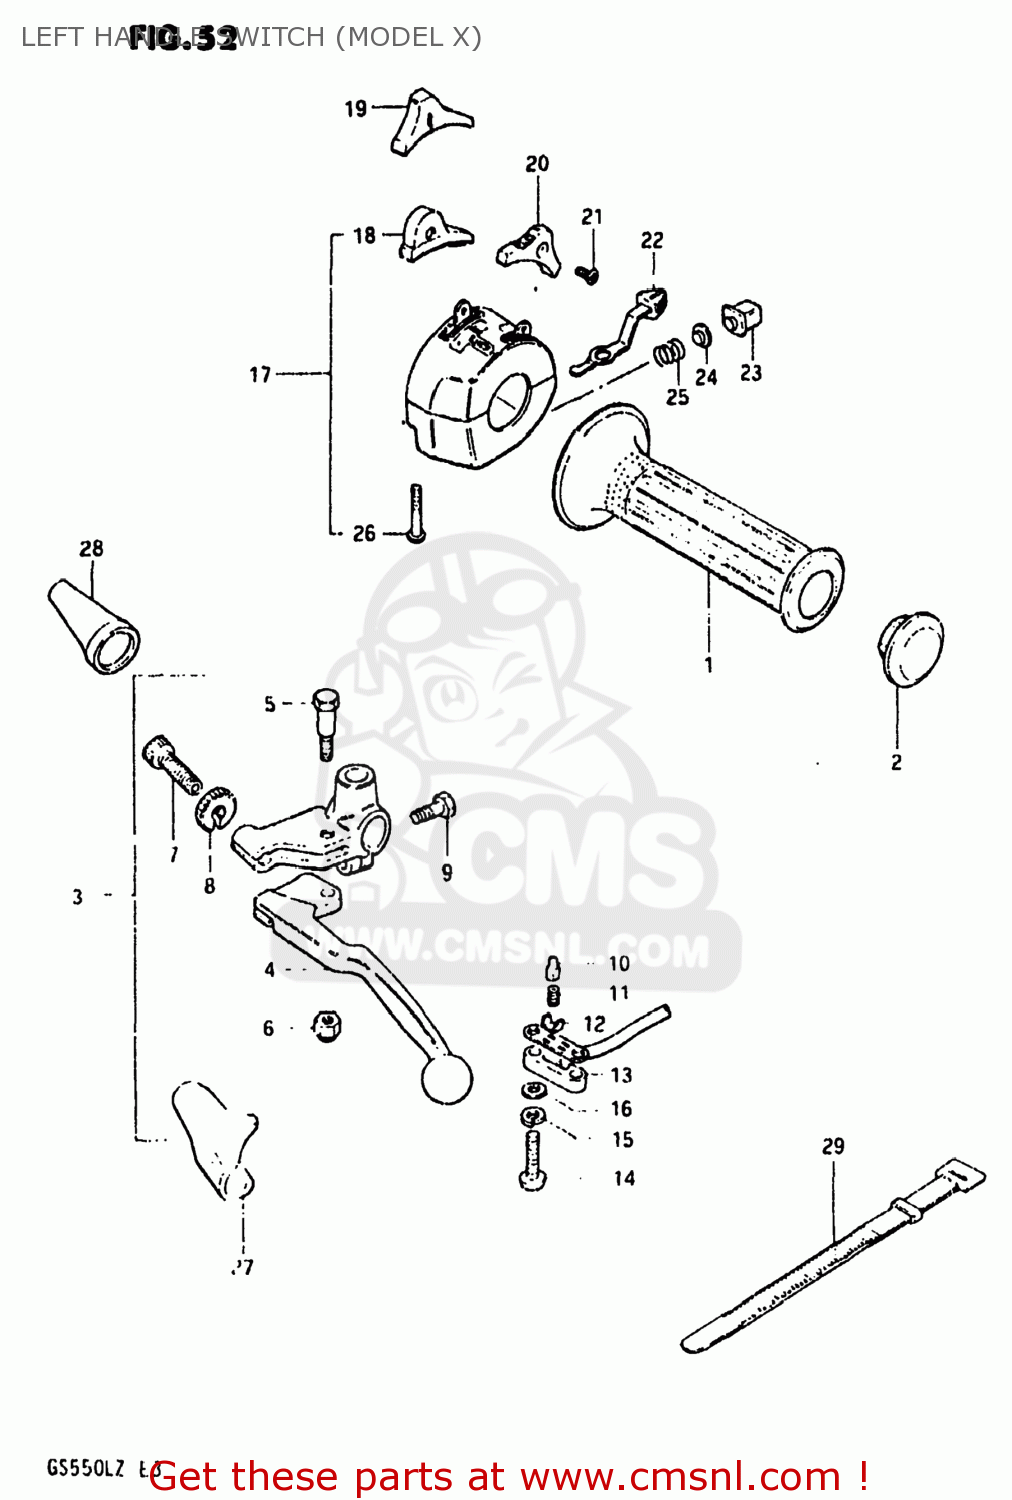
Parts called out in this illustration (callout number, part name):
1	GRIP,LEFT
2	CAP,GRIP END
3	LEVER ASSEMBLY
4	LEVER,CLUTCH
5	BOLT,LEVER
6	NUT 6MM
7	ADJUSTER,CABLE
8	NUT,CABLE ADJUSTER
9	BOLT,CLUTCH LEVER HOLDER
10	HOLDER
11	SPRING
12	PLATE
13	COVER,FR BK TERMINAL BASE
14	SCREW
15	LOCK WASHER
16	WASHER
17	SWITCH ASSY,HANDLE,L
18	KNOB,STOP
19	KNOB,LIGHTING SWITCH
20	KNOB,DIMMER SWITCH
21	SCREW
22	KNOB,TURNSIGNAL
23	BUTTON,HORN
24	CONTACT
25	SPRING
26	SCREW
27	COVER,CLUTCH LEVER
28	BOOT,CLUTCH CABLE
29	CLAMP(L:120)
